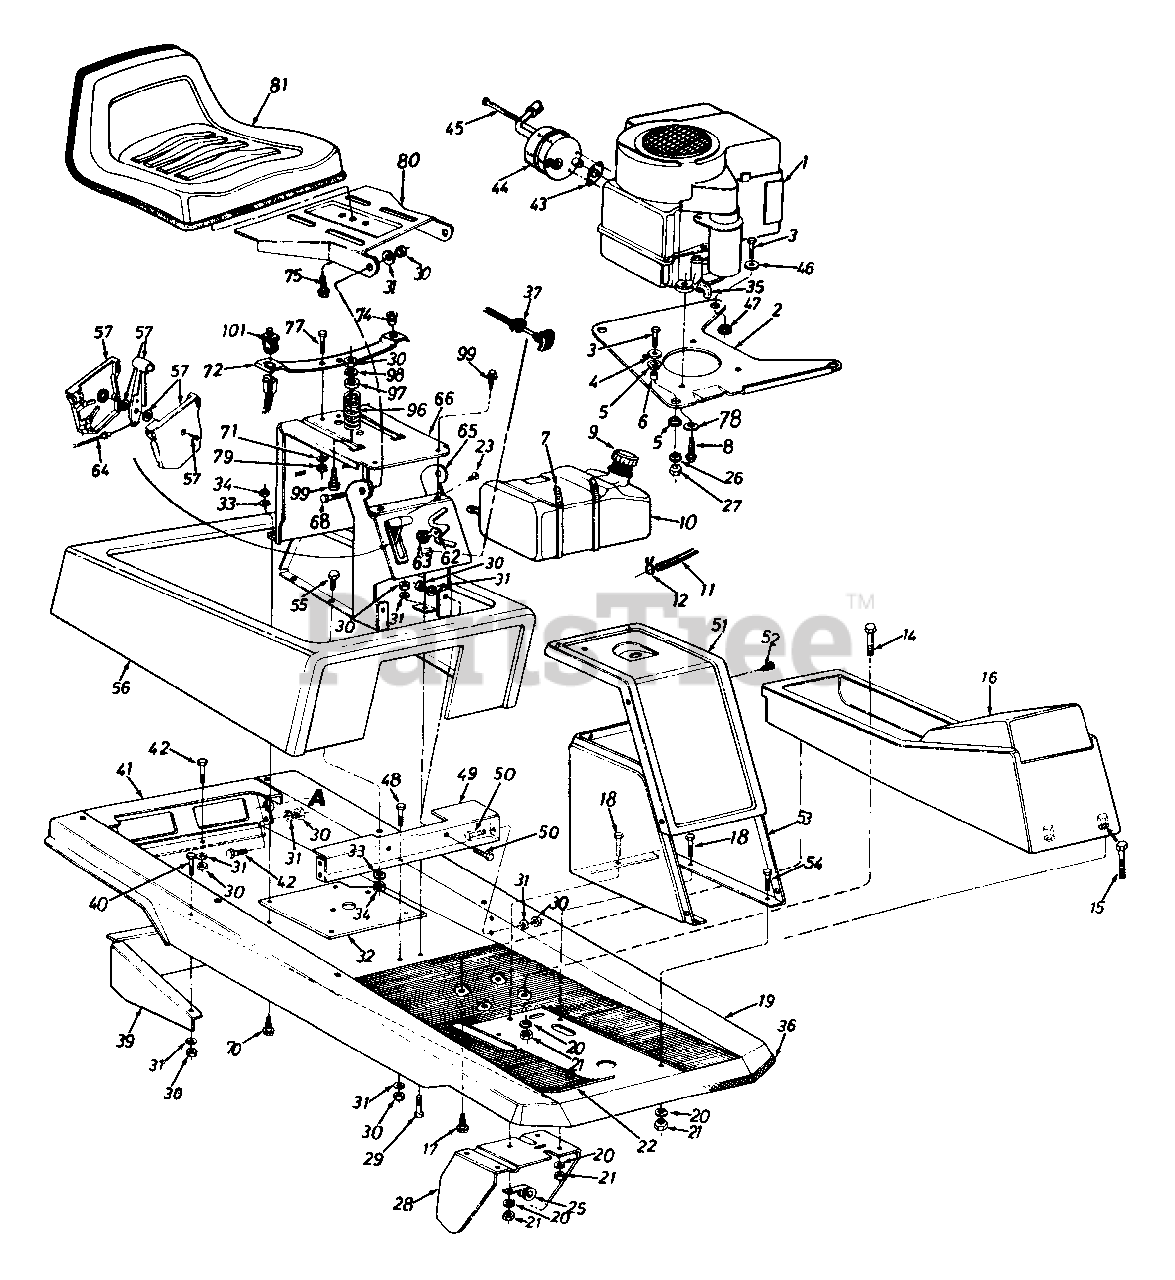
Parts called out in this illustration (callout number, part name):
1	Engine
4	FL--Wash. .330" I.D. x 1.125" O.D.
5	Engine Mounting Grommet
6	Spacer .315" I.D. x .50" O.D. x .520" Lg.
7	Cable Tie 30.6 Lg.
8	Hex Wash. Hd. Self-Tap Scr. 3/8 - 16 x 1.25" Lg.
9	Gas Cap
10	Fuel Tank
11	Fuel Line - 26" Lg.
12	Hose Clamp - 1/2" O.D. Tube
14	Hex Bolt 5/16 - 18 x 1.75" Lg.
15	Hex Bolt 5/16 - 18 x 2" Lg.
16	Front Console
17	Plastite Scr. 5/16 x 1.25" Lg.
18	Hex Bolt 5/16 - 18 x .75" Lg.
19	Main Frame
20	L-Wash. 5/16" I.D.
21	Hex Nut 5/16 - 18 Thd.
22	Floor Mat
23	Truss Mach. AB-Tap Scr. #10 x .50" Lg.
25	Clamp
26	L-Wash. 5/16" I.D.
27	Hex Nut 5/16 - 24 Thd.
28	Clutch - Brake Pedal Ass'y.
29	Hex Bolt 5/16 - 18 x .75" Lg
30	Hex Nut 5/16 - 18 Thd.
31	L-Wash. 5/16" I.D.
34	Hex Nut 1/4 - 20 Thd.
35	90ø Elbow Male To Female
36	Trim Strip
37	Choke Control
43	Exhaust Gasket
44	Muffler Ass'y.
45	Shld. Bolt
46	FL-Wash. .330" 1.D. x 1.25" O.D.
47	Flange Wash. .320" I.D. x .750" O.D.
49	Seat Support & Frame Brkt.
50	Hex Bolt 5/16 - 18 x .75" Lg.
55	Hex Bolt 1/4 - 20 x .50" Lg.
62	Ignition Key
63	Ignition Switch
64	Throttle Control Wire 35" Lg.
70	Hex Tap Scr. 1/4 - 20 x 1.0" Lg.
71	L-Wash. 5/16" I.D.
72	Seat Spring
74	Grommet
75	Hex Bolt 3/8 - 16 x .62" Lg. (Gr. 5)
77	Hex Bolt 5/16 - 18 x .75" Lg.
78	Bell-Wash. .345" I.D. x .88" O.D.
79	Hex Cent. L-Nut 5/16 - 18 Thd.
81	Seat Ass'y. Comp.
96	Compression Spring 2.7" Lg.
97	Bushing
98	FL-Wash. .344" I.D. x .875"
99	Hex Bolt 5/16 - 18 x 1" Lg. (Gr. 5)
101	Seat Switch
